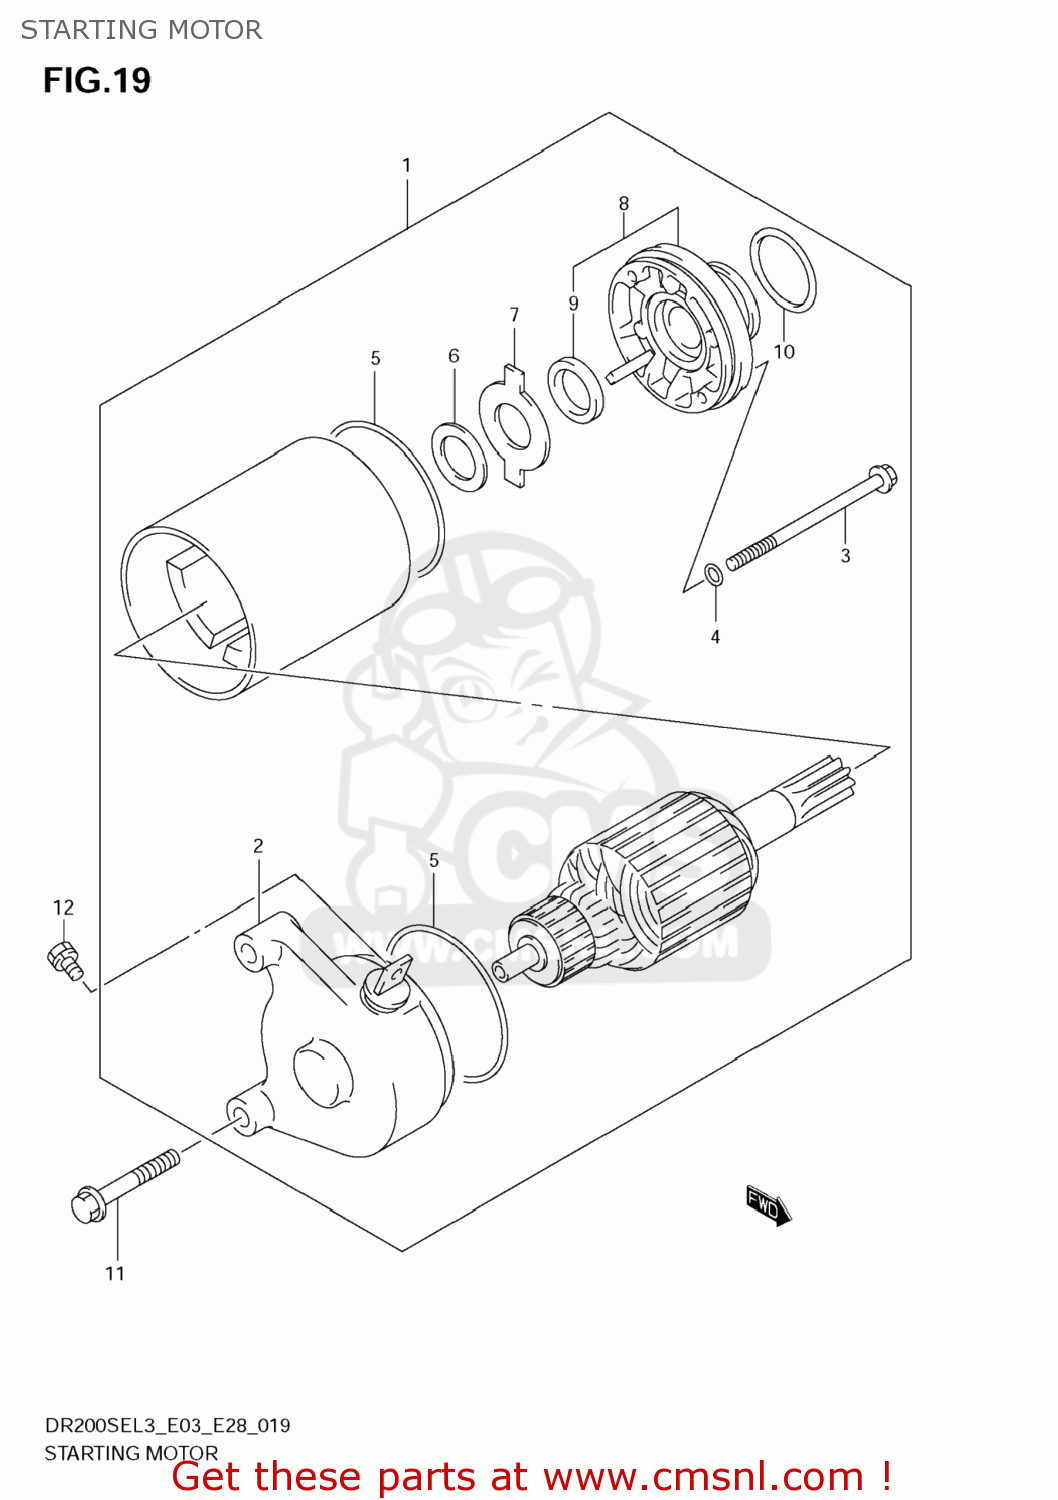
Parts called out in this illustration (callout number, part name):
1	MOTOR ASSY,STARTING
2	FRAME ASSY,COMMUTATOR END
3	BOLT
4	O RING
5	O RING
6	SHIM
7	PLATE,LOCK
8	BRACKET
9	SEAL,OIL
10	O RING(D:3,ID:24.5)
11	BOLT
12	SCREW(5X8)
